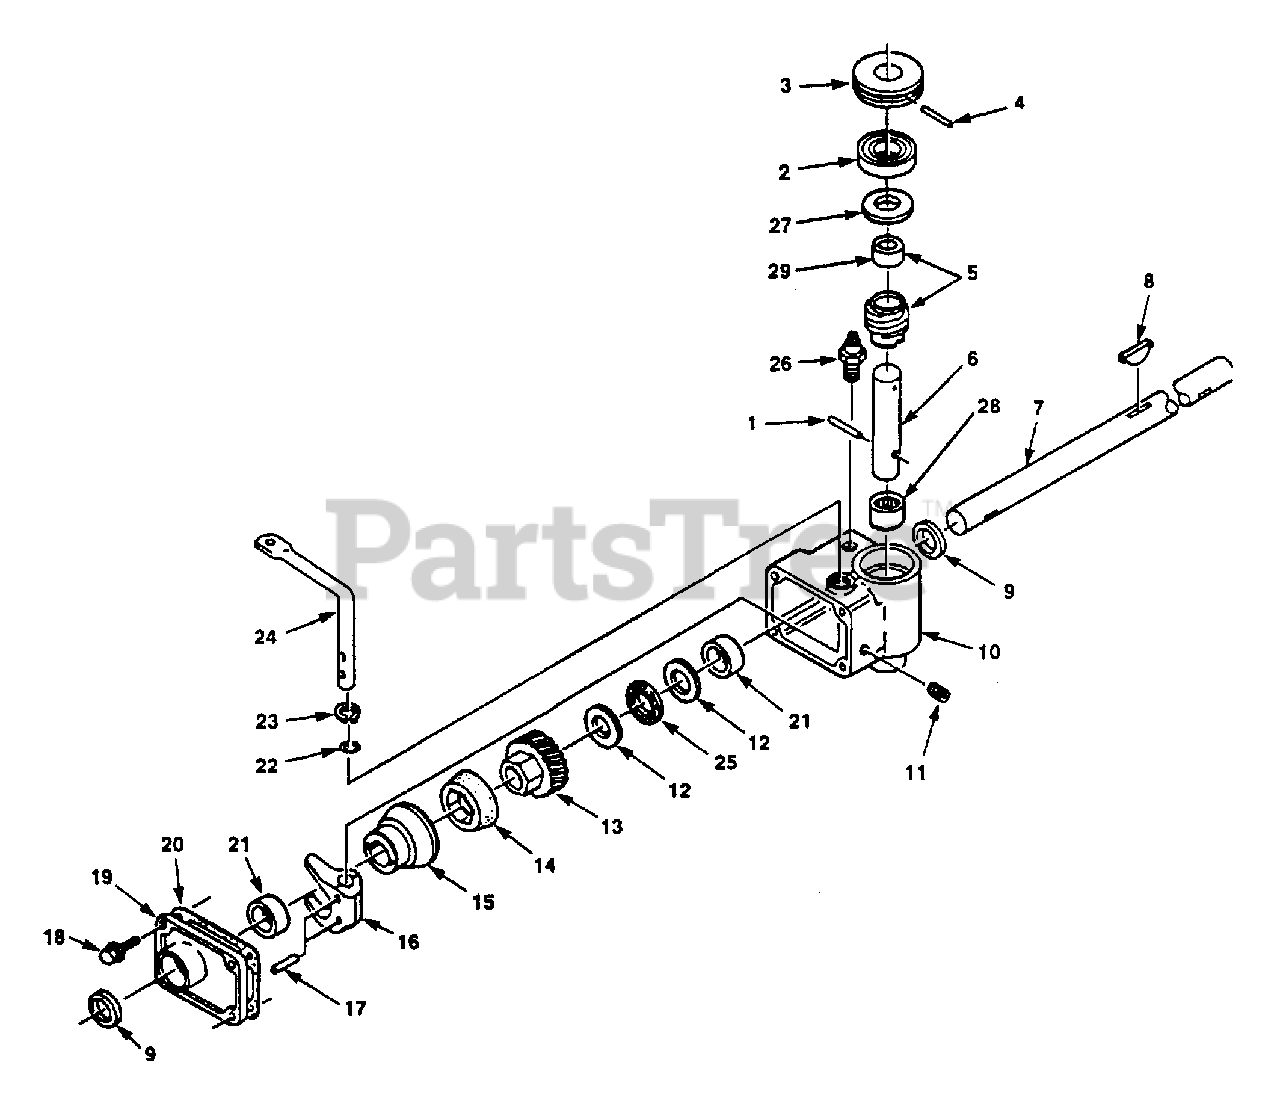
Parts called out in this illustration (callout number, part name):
1	PIN
2	BEARING, BALL
3	PULLEY
4	PIN 3/32×3/4
5	WORM & SPACER
6	SHAFT, WORM
7	SHAFT, DRIVE
8	KEY - 1/8×1/2"
9	SEAL
10	GEAR REDUCER HOUSING ASSY
11	PLUG - PIPE
12	RACE - BEARING
13	GEAR, WORM
14	CONE - FRICTION
15	DRUM, CLUTCH
16	FORK - SHIFT
17	PIN 5/32×3/4
18	SCREW - 1/4-20×7/8"
19	LID, GEAR CASE
20	GASKET
21	BUSHING - SLEEVE
22	O-RING
23	RING
24	LEVER, SHIFT
25	BEARING - THRUST
26	VENT
27	WASHER
28	BEARING, NEEDLE
29	SPACER
